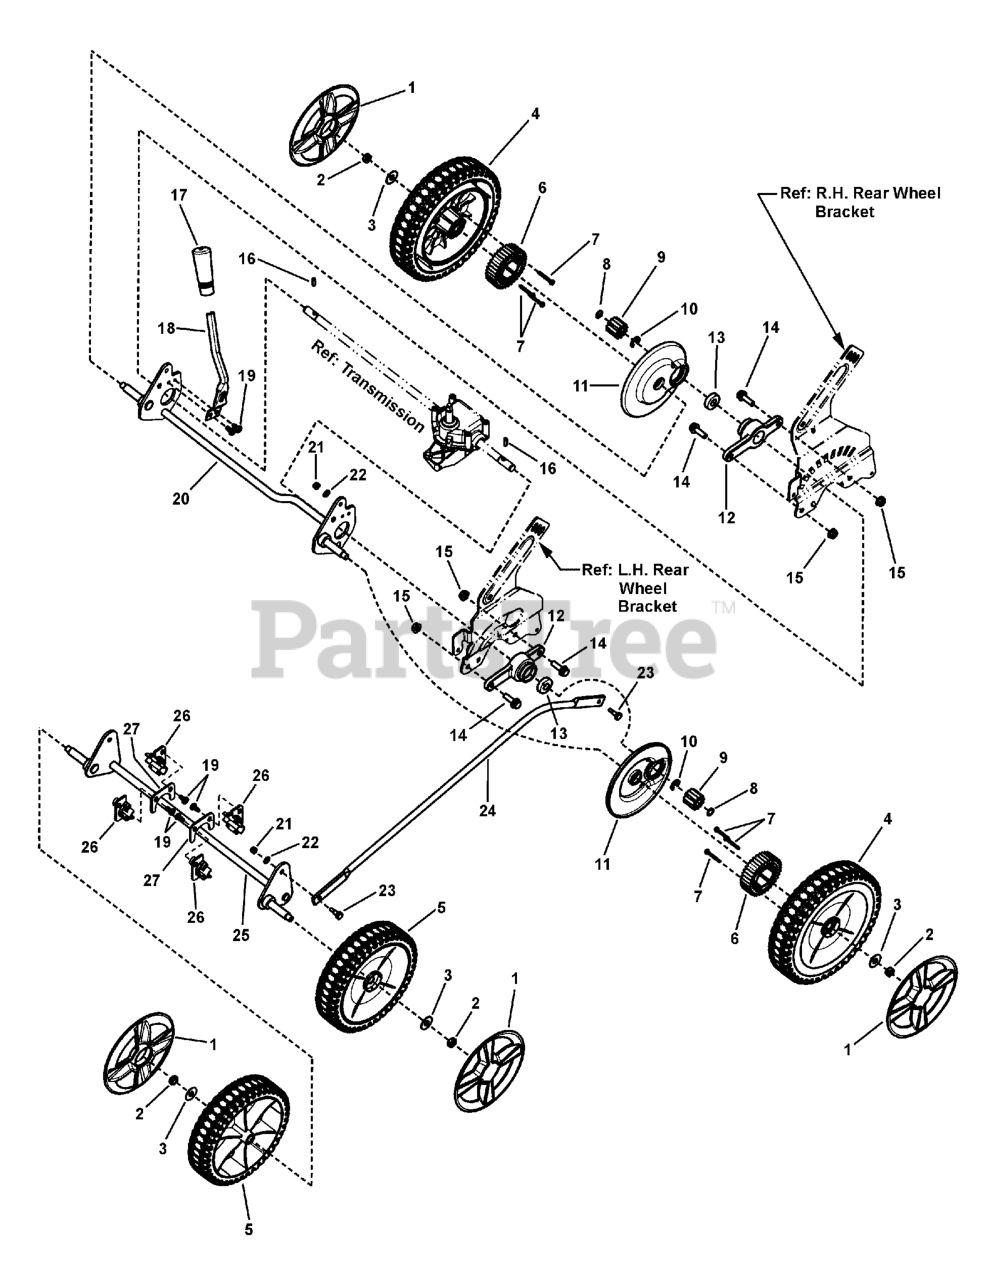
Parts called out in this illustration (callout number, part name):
1	HUBCAP, 8"& 9" Wheel Spoked, P-391 St Yellow
2	NUT, 3/8-16 Hex Center Lock Jam YZ
3	WASHER, 1" O.D. x .387 I.D. Flat
4	Wheel, 9" x 2"
5	WHEEL, 8" x 2" Idle w/Db Trd, Brute, Satin Black
6	GEAR, External Wheel
7	SCREW, #8 x 1-1/4" Hi-Lo Hex washer Self-Tap
8	RETAINING RING
9	GEAR, Pinion
10	RING, External Retaining
11	DUST SHIELD, 21" WBM, RD
12	HOLDER, Bearing, RWD
13	BEARING, Ball
14	BOLT, 5/16-18 x 1" Hex Flange Lock, GR 5, YZ
15	NUT, 5/16-18 Hex Flange Lock, YZ
16	PIN, Axle
17	GRIP, Height-Of-Cut
18	LEVER, Spring, Height-Of-Cut
19	SCREW, 1/4-20 x .550 Pan Head Torx (T-30)
20	WELDMENT, Rear Crossbar, RWD
21	NUT, #10-24 Hex Lock (Nyloc)
22	WASHER, .219 x 1/2" x .049 Flat
23	SHOULDER BOLT, #10-24
24	ROD, Lifter Link, WBM
25	WELDMENT, Front Crossbar
26	BUSHING, Bearing, RWD
27	PLATE, SUPPORT, FRONT BUSHING
